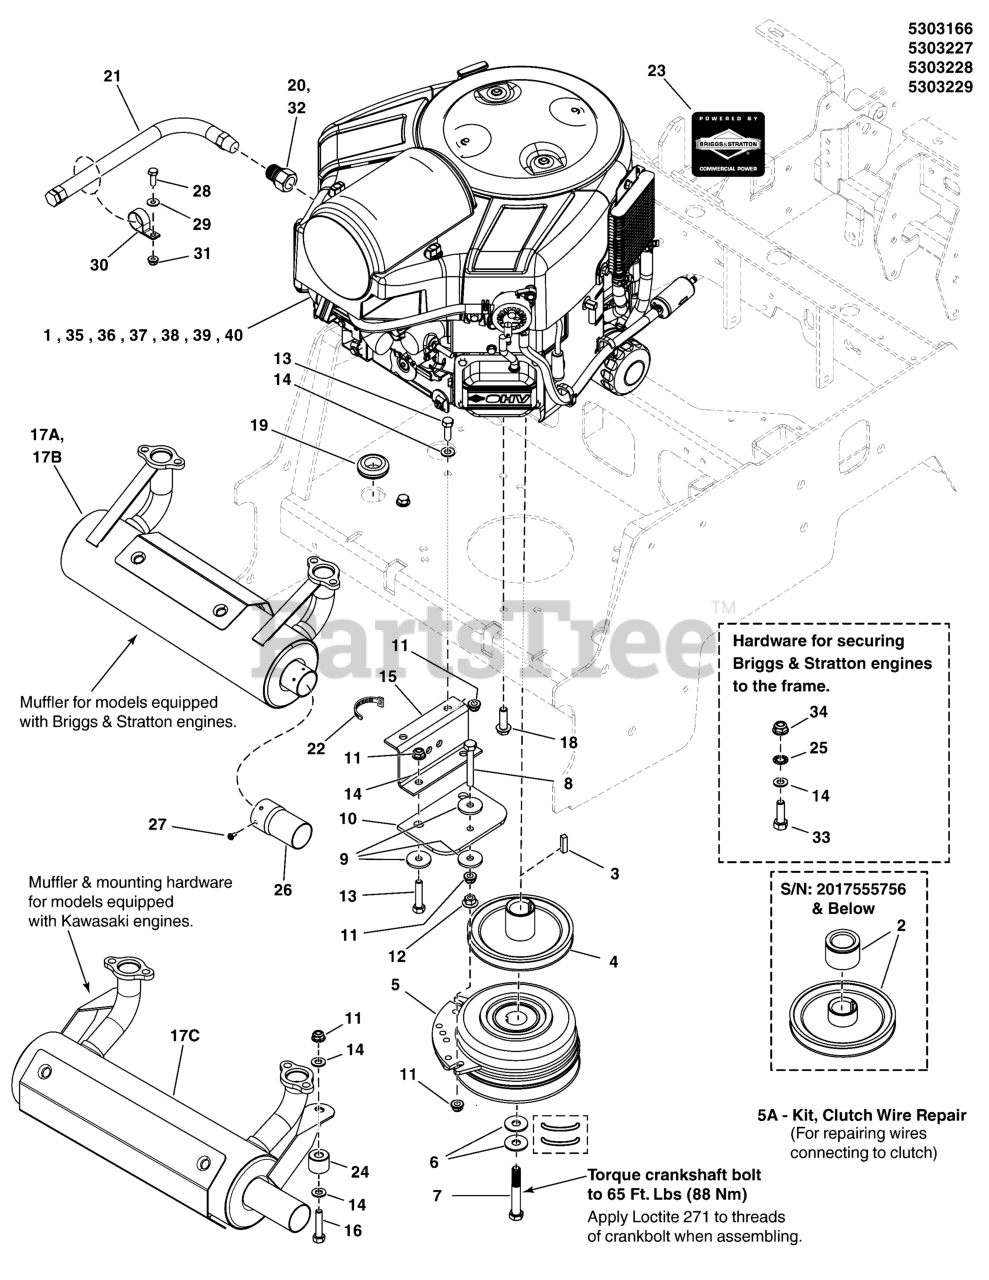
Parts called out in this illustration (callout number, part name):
3	KEY 1/4 SQ X 1 1/2 LONG
4	PULLEY, CRANKSHAFT 1.1255"ID X 5.318" OB
5	CLUTCH WARNER 200 FT-LB 1.13 X 6.323
5A	KIT, CLUTCH WIRE REPAIR
6	BELLEVILLE WASHER, 1.1875 X .442 X .098
7	BOLT, CRANKSHAFT, 7/16-20 X 3, GD8
8	BOLT, 5/16-18 X 2-1/4 TFL, GD5 YZ
9	WASHER, .34 X 1.25 X 10 GA
10	CLUTCH ANCHOR PAD
11	NUT, 5/16-18 HEX NYLOCK FLANGE NUT
12	NUT, 5/16-18 HEX SERRATED FLANGE (LARGE)
13	BOLT, 5/16-18 X 1" GRD5 YZ
14	WASHER, 5/16" SAE
15	ANCHOR, CLUTCH, IS600-IS700 - BLK
16	BOLT, 5/16-18 X 1-3/4" GD5 YZ
17A	MUFFLER, RIGHT OUTLET ASSY
17B	MUFFLER (Purchase from Engine Manufacturer)
17C	MUFFLER, KAWI, HORIZONTAL, 5" CAN
18	BOLT, HEX FLG, SER, GD5 3/8-16 X 1-1/4" PACH CZ
19	GROMMET, 7/8"
20	ADAPTER, Oil Drain
21	HOSE, OIL DRAIN
22	TIE,SELF-LOCKING, 24"
24	SPACER, .39 X 1.00 X .80, CZ
25	WASHER, 5/16" Internal Tooth Lock
26	EXTENSION, TAILPIPE, 3" - BLACK
27	SCREW, SELF-TAP, #8-32 X 3/8. WASH HEX, CZ
28	BOLT, 1/4"-20 X 3/4" GD5 YZ
29	WASHER, 1/4 SAE
30	CLAMP, VINYL INSULATED, 1.00
31	NUT, 1/4-20 Hex Nylock Flange
32	METRIC ADAPTER, M14-1.5" TO 3/8 NPTF
33	BOLT, 5/16-24 X 1-3/4, GD8, PHOS
34	NUT, 5/16-24, TOP LOCK FLANGE, GD8 PHOS
40	ENGINE, KAWASAKI, FS730V, EFI
40	ENGINE, KAWASAKI, FT730V, EFI
